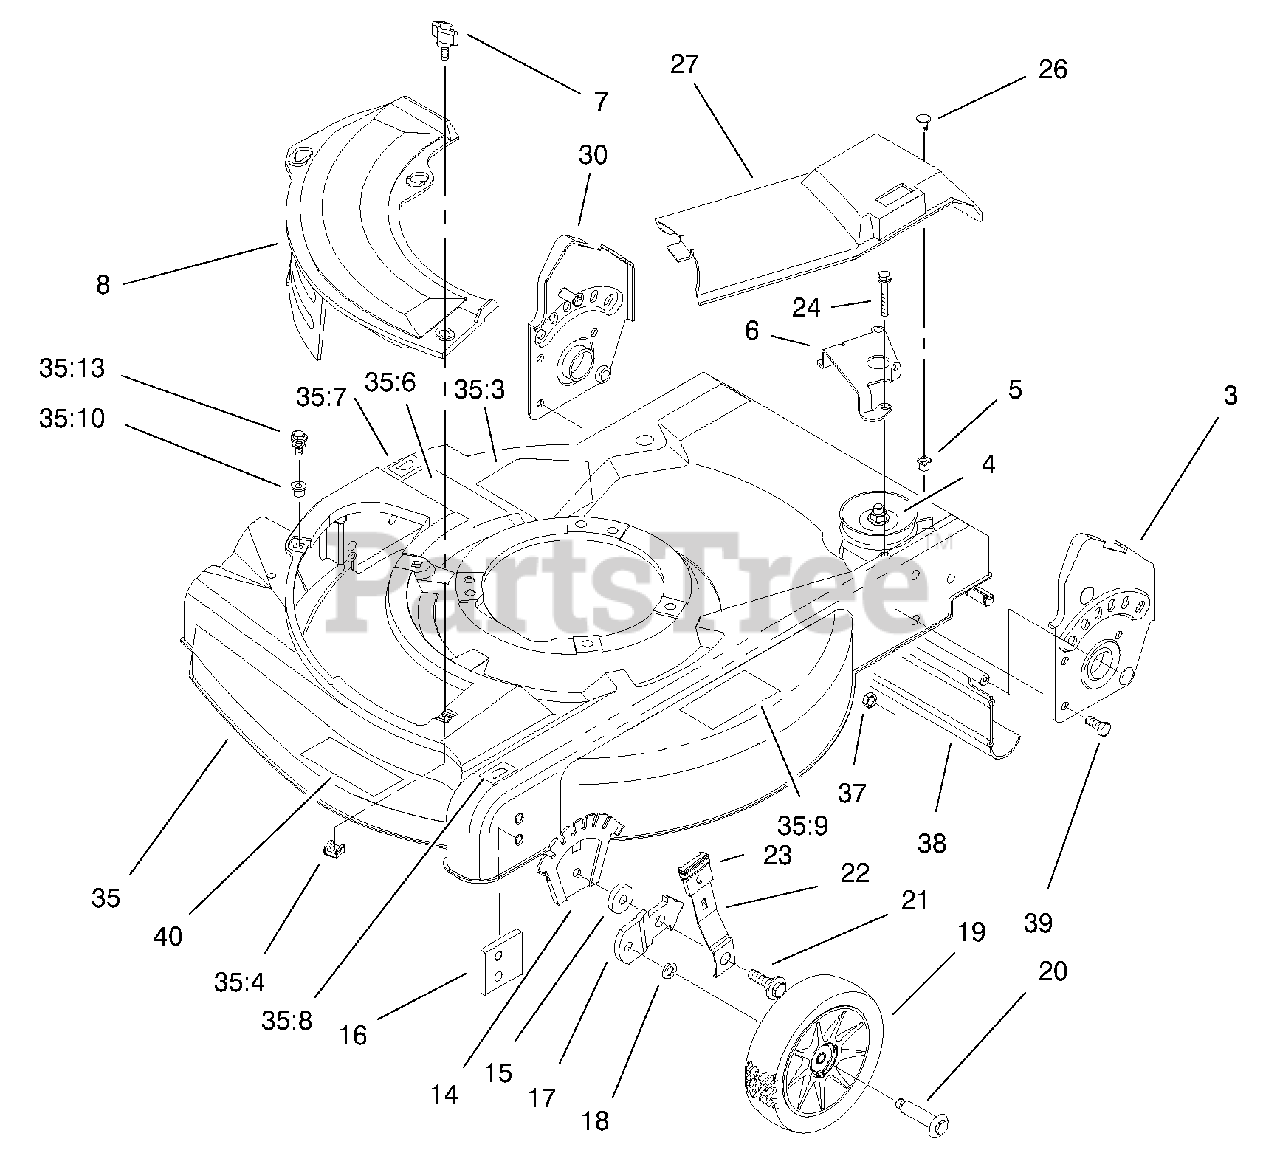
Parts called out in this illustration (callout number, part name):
3	LH Handle Bracket ASM
4	Gear Case ASM
5	Grommet
6	Guide-Transmission
8	Plate-Mulch
14	Plate-Height Adjustment
15	Washer-Wheel
16	Plate-Baffle
17	Bracket-Wheel Height Adjustment
19	Wheel & Tire ASM
20	Bolt-Shoulder
21	Bolt-Shoulder
22	Arm-Front Spring
23	Knob-Lever, Height Adjustment
24	Screw-Thread Forming
27	Cover-Drive
30	RH Handle Bracket ASM
35	Deck ASM
35:3	Decal-Danger
35:4	Nut-Cage
35:6	Decal-Warning
35:7	Decal-HOC, RH
35:8	Decal-HOC, LH
35:9	Decal-Warning
35:10	Grommet-Plastic
35:13	Screw-Sems
37	Nut-Lock, NI
38	Shield-Trailing
39	Screw-HH
40	Decal-Deck
